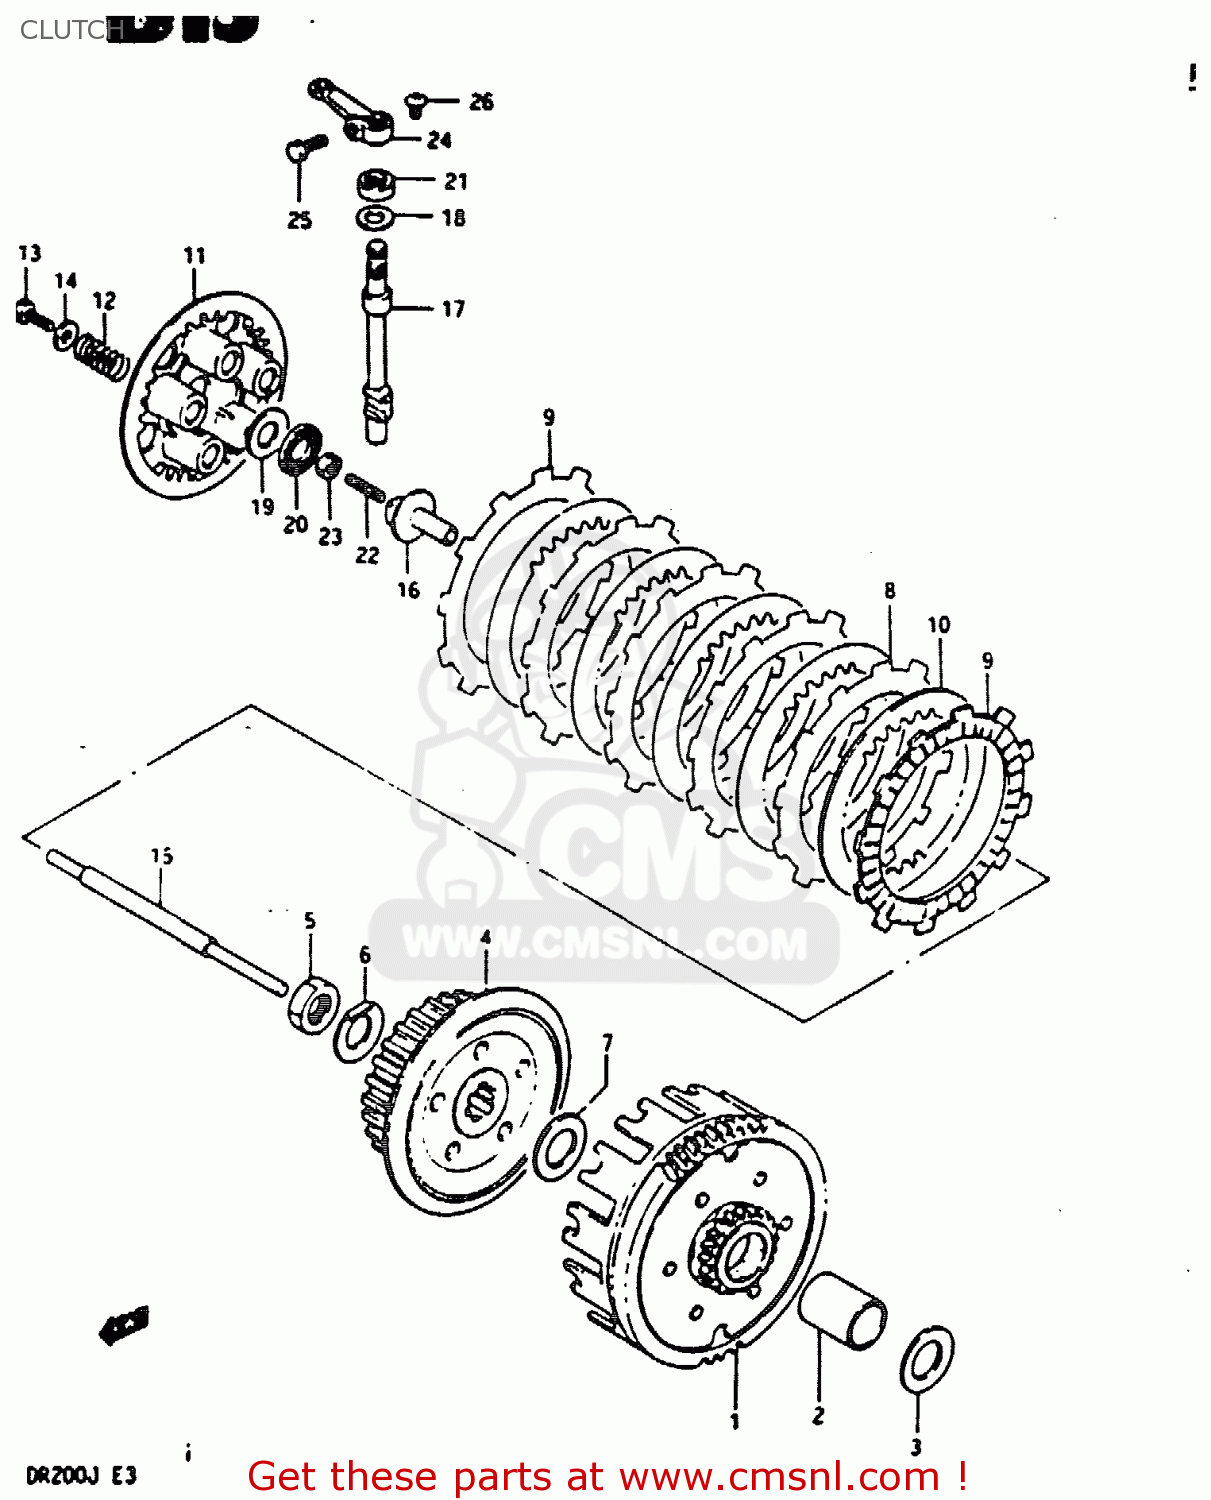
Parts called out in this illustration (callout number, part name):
1	GEAR ASSEMBLY,PRIMARY DRIVE
2	SPACER
3	WASHER
4	HUB,CLUTCH SLEEVE
5	NUT
6	WASHER
7	WASHER
8	PLATE,CLUTCH DRIVE (MCA)
9	PLATE,CLUTCH DRIVE (NAS)
10	PLATE,CLUTCH DRIVEN (NAS)
11	PLATE,CLUTCH PRESSURE
12	SPRING
13	BOLT(5X16)
14	WASHER (5.5X16X1.2)
15	ROD,CLUTCH PUSH
16	PIECE,CLUTCH PUSH
17	CAMSHAFT,CLUTCH RELEASE
18	WASHER,THRUST
19	WASHER
20	BEARING(15X28X2)
21	OIL SEAL
22	SCREW(6X25)
23	NUT 6MM
24	ARM,CLUTCH RELEASE
25	BOLT
26	SCREW
